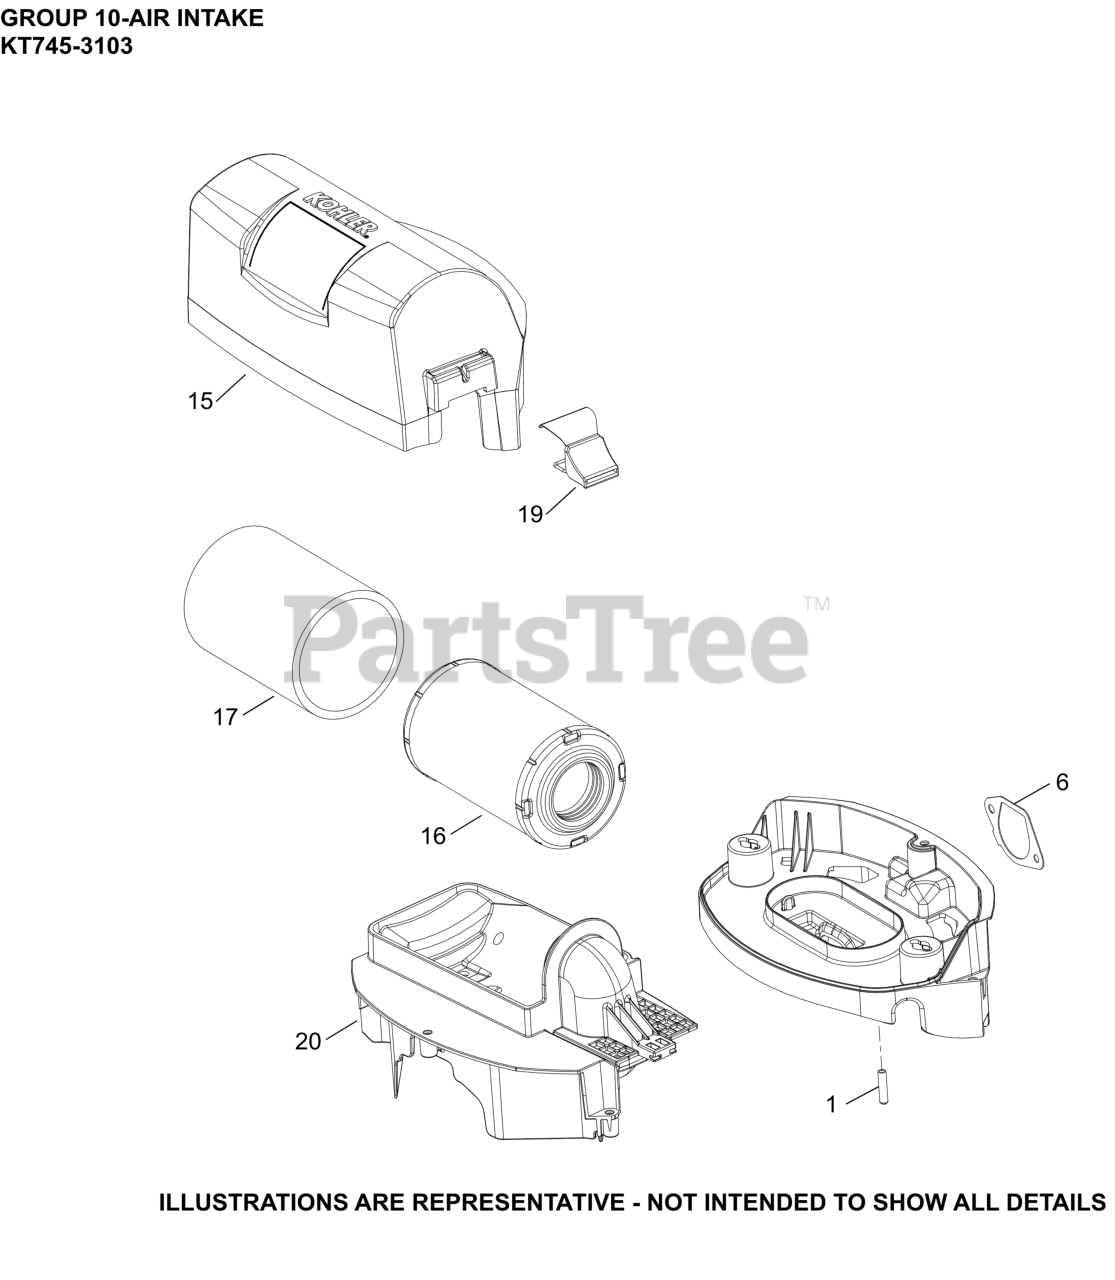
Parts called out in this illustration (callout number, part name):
1	CAP, MASKING
6	GASKET, AIR CLEANER BASE
15	COVER, AIR CLEANER
16	ELEMENT, AIR FILTER
17	ELEMENT, PRE-CLEANER
19	LATCH ASSY, AIR CLEANER COVER
20	BASE, ASM. AIR CLEANER (CYLINDRICAL)
